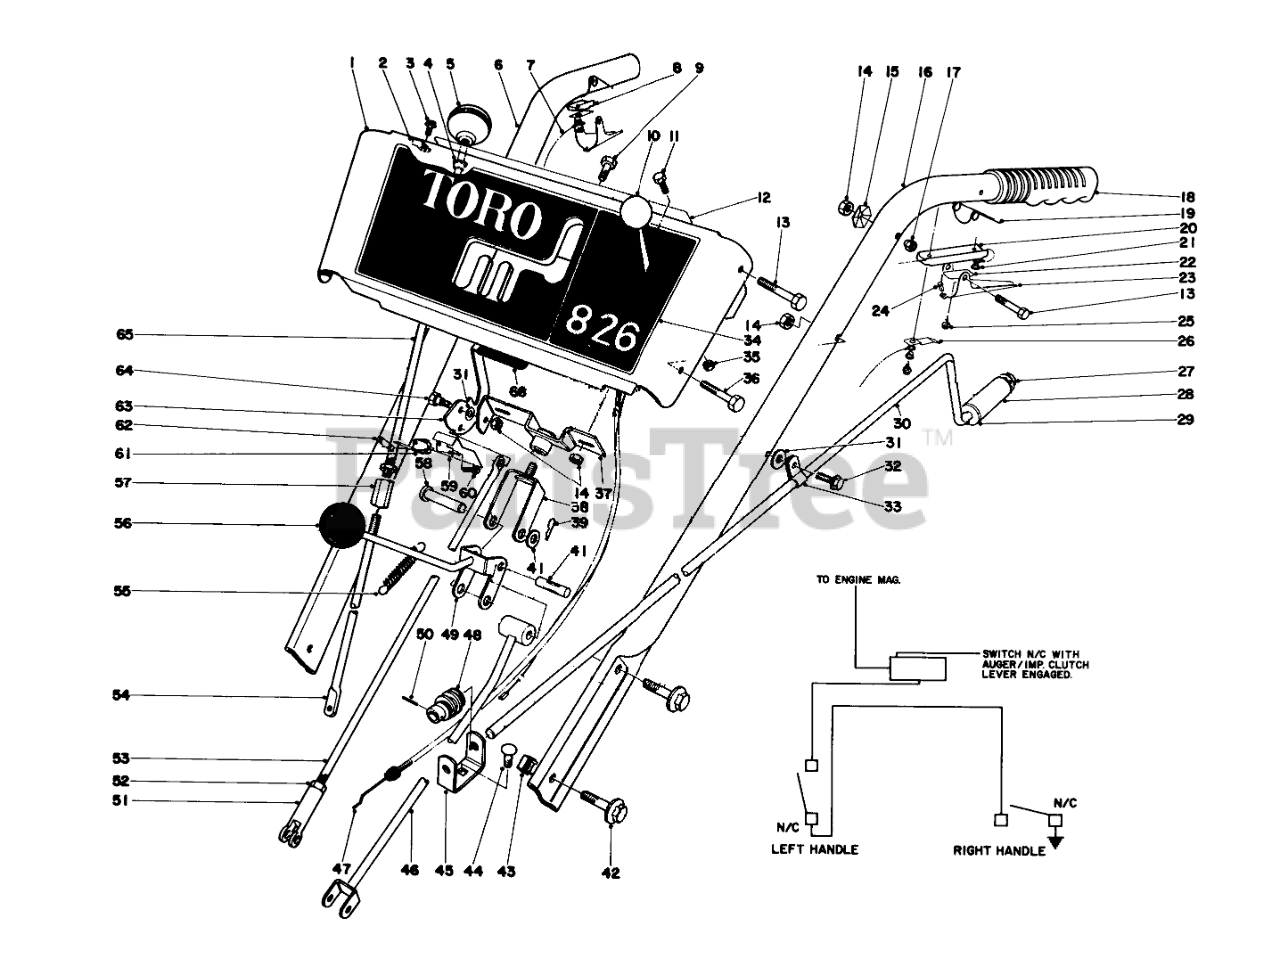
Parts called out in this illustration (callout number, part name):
1	Escutcheon Plate (Incl. Ref. #12 & 34) (Model #31823 Only)
2	PLASTIC CLIP
3	SCREW-HWHTF
4	NYLINER #6LI-FF TYPE 7
5	KNOB-LEVER
6	Handle Right
7	WIRE HARNESS
8	Insulator
9	SCREW-HH
10	KNOB-CONTROL
11	HEX HEAD SEMS 10-24X1/2
12	Decal
13	SCREW-HH
15	Washer
16	Handle Left
17	NUT-CAP
18	Grip Handle
19	INTERLOCK SPRING
20	Insulator
21	WASHER INSULATOR
22	INTERLOCK CONTACT
23	Safety Lever
24	1/4 PLASTIC RIVET
25	Screw
26	CONTACT BRACKET
27	RETAINER-PUSH ON
28	CHUTE CONTROL GRIP
29	WASHER-FLAT
30	ROD CHUTE CONTROL
31	Washer
32	SCREW-HWHTF
33	R-CLAMP
34	Decal-Escutcheon (Model #31763)
35	Nut
36	SCREW-HH
37	SWIVEL BLOCK WA
38	Pivot Bracket
39	PIN-HAIR
40	WASHER-FLAT
41	3/8 X 1-1/4 ROL
42	SCREW-HHF
43	Retained Nut
44	SCREW-CARR
45	WORM BRACKET
46	Trunnion
47	Throttle Contrl
48	GEAR-WORM, CHUTE
49	Rod Shift
50	PIN-SPRING
51	Clevis
52	NUT-HJ
53	DRAG LINK
54	LOWER WHL CLUTCH ROD
55	CONT ROD SPRING 0
57	WHL ROD COUPLING
58	PIN-CLEVIS
59	SWITCH BRKT
60	Pan Hd. Machine Screw
61	MICRO SWITCH
62	NUT-SPEED
63	Auger Clutch Handle
64	SCREW-SHOULDER
65	Rod Wheel Clutch
66	AUGER CLUTCH HND GRIP
